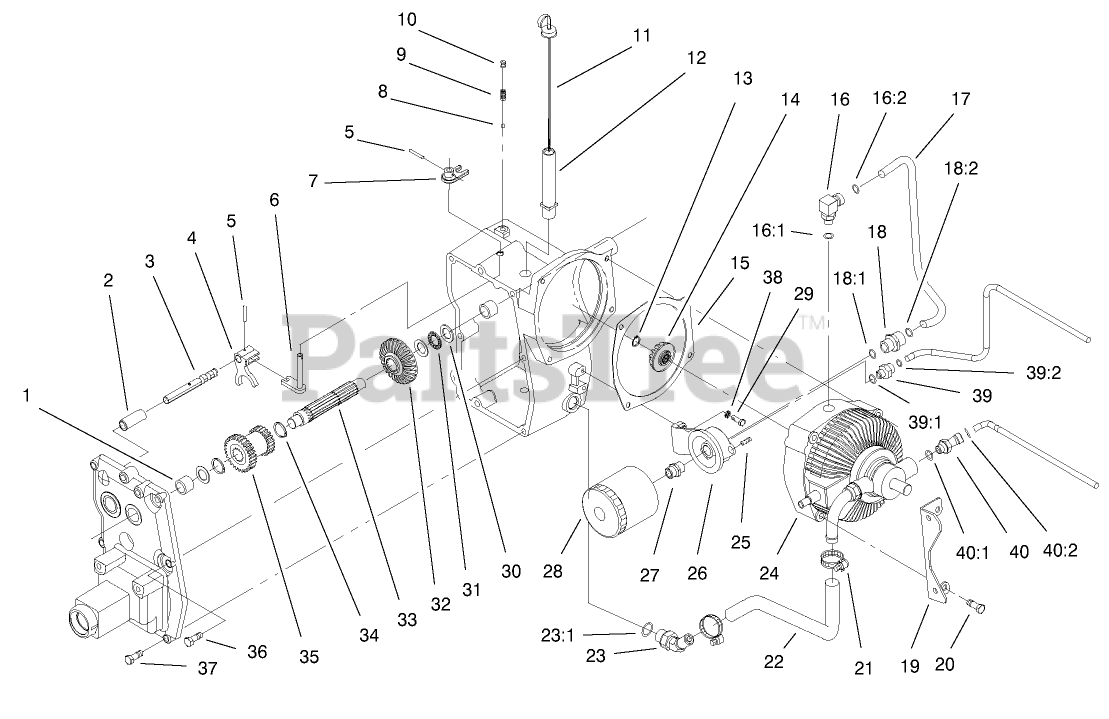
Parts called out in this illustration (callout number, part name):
1	BEARING-NEEDLE
2	TUBE-RAIL, SHIFTER
3	RAIL-SHIFT
4	FORK-HI / LO SHIFT
5	PIN-ROLL
6	ARM-SHIFTER
7	SHIFT-HI / LO
8	BALL-DETENT
9	SPRING-DETENT, SHIFT
10	SCREW-SET, HSH
11	DIPSTICK
12	TUBE-DIPSTICK
13	RING-SNAP, EXTERNAL
14	PINION-BEVEL
15	GASKET
16:1	O-RING
16:2	O-RING
17	TUBE-HYD
18:1	O-RING
18:2	O-RING
19	PLATE-BRACKET, SUPPORT
20	SCREW-HH
21	CLAMP-DRIVE, WORM
23:1	O-RING
24	TRANSMISSION-HYDRO
25	PLUG-PIPE
26	BASE-FILTER
27	FITTING
28	OIL FILTER ASM
29	SCREW-HH
30	WASHER-THRUST
32	GEAR-BEVEL
33	SHAFT-INPUT
34	RING-RETAINING
35	GEAR HI / LO
36	SCREW-HH
37	SCREW-HH
38	WASHER-LOCK
39:1	O-RING
39:2	O-RING
40:1	O-RING
40:2	O-RING
